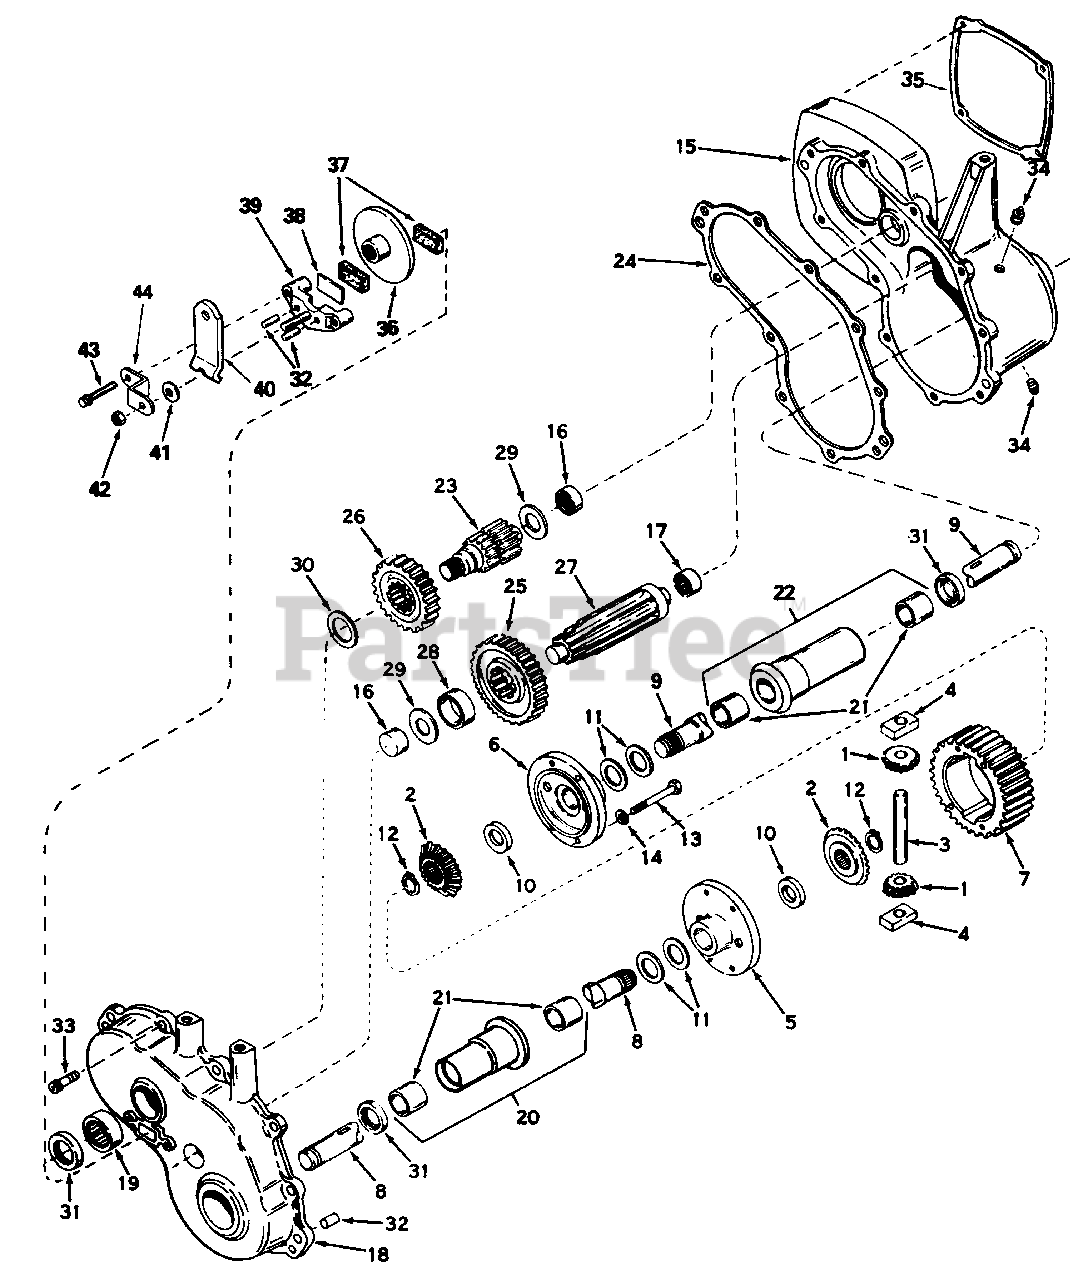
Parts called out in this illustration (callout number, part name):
1	PINION, Bevel
2	GEAR, Bevel
3	PIN, Drive
4	BLOCK, Drive
5	CARRIER, Differential
6	CARRIER, Differential
7	GEAR, Ring
8	AXLE, (12-3/4" long)
9	AXLE, (14-23/32" long)
11	WASHER, Thrust
12	RING, Snap
13	SCREW, Hex Hd., 1/4-20 x 2-1/4
14	LOCKWASHER, 1/4"
15	CASE ASSY. (Incl. Nos. 16 & 17)
16	BEARING, Needle
17	BEARING, Needle
18	COVER ASSY. (Incl. Nos. 16 & 19)
19	BEARING, Needle
20	HOUSING & BUSHING ASSY. (6-5/8" long)(Incl. 2 No. 21)
22	HOUSING & BUSHING ASSY. (8-5/8" long)(Incl. 2 No. 21)
23	SHAFT, Brake
24	GASKET, Case-to-Cover
25	GEAR, Output
26	GEAR, Idler
27	SHAFT, Output
31	SEAL, Oil
32	PIN, Dowel
33	SCREW, Hex Washer Hd., Thread Forming, 1/4-20 x 1
34	PLUG, Pipe
36	DISK, Brake
37	PAD, Brake
38	PLATE, Brake Pad
39	HOLDER, Brake Pad
40	LEVER, Brake
41	WASHER, Flat
42	LOCKNUT, 5/16-24
43	SCREW, Hex Hd., Thread Forming, 1/4-20 x 1-1/4
